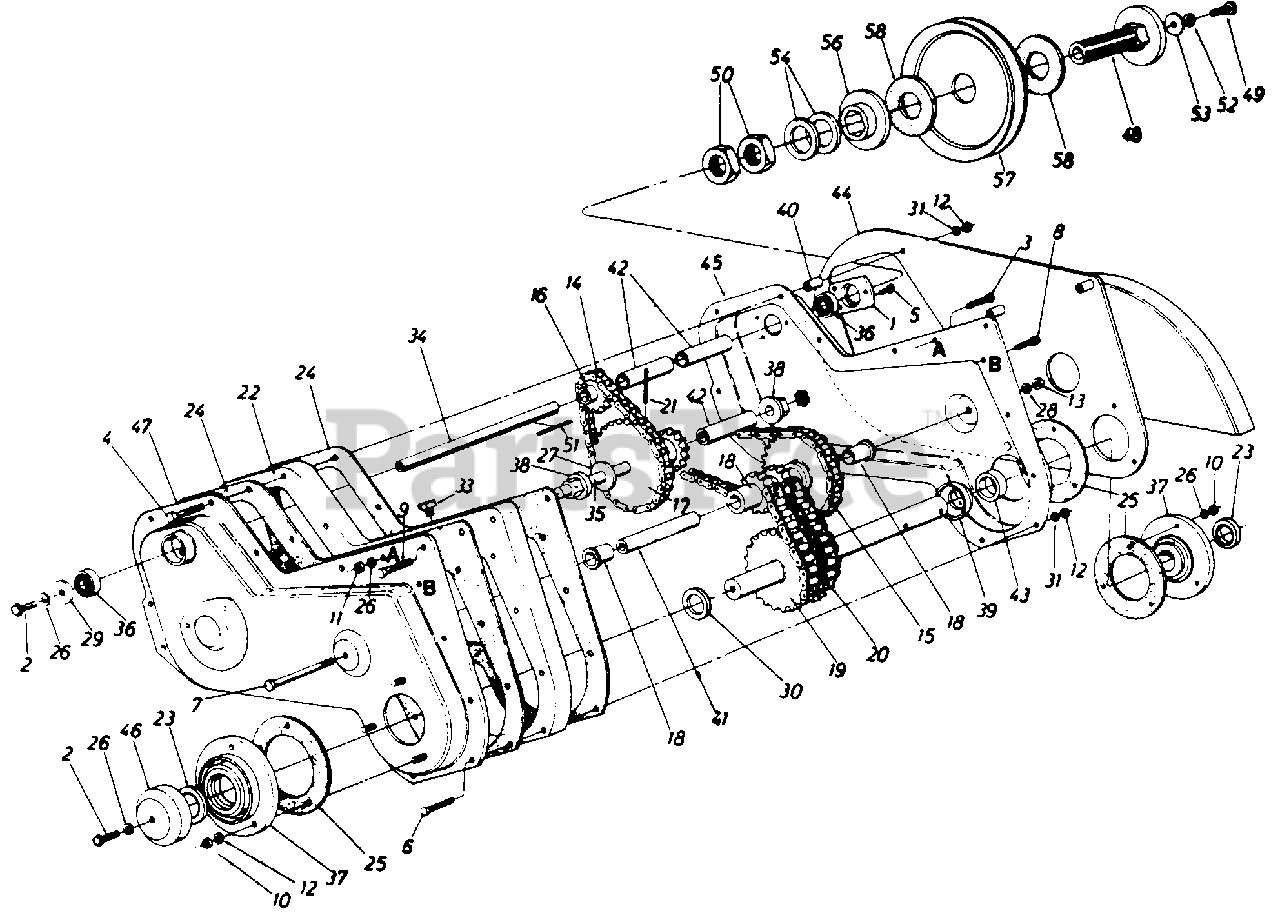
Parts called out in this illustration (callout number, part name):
1	Bearing Housing 1-3/8" Dia.
2	Hex Bolt 5/16-18 x .88"
3	Hex Bolt 5/16-18 x 1.5" Lg.
4	Hex Bolt 1/4-20 x 2.75" Lg.
5	Hex S-Tap Scr. 1/4-20 x .5" Lg.
6	Hex Bolt 1/4-20 x 1.5" Lg.
7	Hex Bolt 3/8-16 x 4.5" Lg.
8	Hex Scr. 1/4-20 x 1.5" Lg.
8	Hex TT-Tap Scr. 5/16-18 x 1.75
10	Hex L-Nut 5/16-18 Thd.
11	Hex Nut 5/16-18 Thd.
12	Hex Nut 1/4-20 Thd.
13	Hex Nut 3/8-16 Thd.
14	#41 Chain1/2" Pitch x 34 0 Links-Endless
15	#42 Chain1/2 Pitch x 48 0 Links-Endless
16	Sprocket 10 Tooth .5" Pitch
17	10 & 28 Teeth Sprocket Ass'y.
18	8-2 & 28 Sprocket Sleeve Ass'y.
19	18-2 Sprocket Shaft Ass'y.
20	#50-2 Chain 5/8u Pitch x 28 0 Links-Endless
21	Spring Pin Spir. 1/4" Dia. x 1 .5" Lg.
22	Spacer Block-Tiller Housing
23	Oil Seal 1-1/4" Dia.
24	Gasket for Tiller Housing
25	Gasket for Brg. Housing
26	L-Wash. 5/16" I.D.
27	Fl-Wash. .64" I.D. x 1.24" O.D.
28	L-Wash. 3/8" I.D.-H.D.
29	Fl-Wash. .344" I.D. x 1.125"
30	Special Washer
31	L-Wash. 1/4" I.D.
33	Vent Plug
34	Jack Shaft .525" I.D. x 7.78"
35	SprocketShaft .63" Dia. x 5"
36	Ball Brg. .62" I.D. x 1.38" O.D.
37	Bearing Housing-1-1/4"
38	Hex Flange Brg.
39	Spacer 1.25" I.D. x 2.0" O.D.
40	Spacer .9" Lg.
41	Spacer3.44" Lg.
42	Spacer 1.56 Lg.
43	Spacer 5u Lg.
46	Dust Cap
49	Hex Bolt 5/16-18 x 1.25" Lg. Grade 5
50	Hex Jam Nut 1.0-14 x 28 Thd.
51	Sq. Key 3/16 x 1.5" Lg.
52	L-Wash. 5/16" I.D.
53	Fl-Wash. .344" I.D. x 1.125"
54	Bell-Wash. 1.0 I.D. x 2.0"
56	Floating Disc 3-1/4" O.D.
57	5/8 V-Pulley 1.5 I.D. x 6.5"
58	Friction Pad 3-1/4" O.D. x 1-3/8 I.D.
